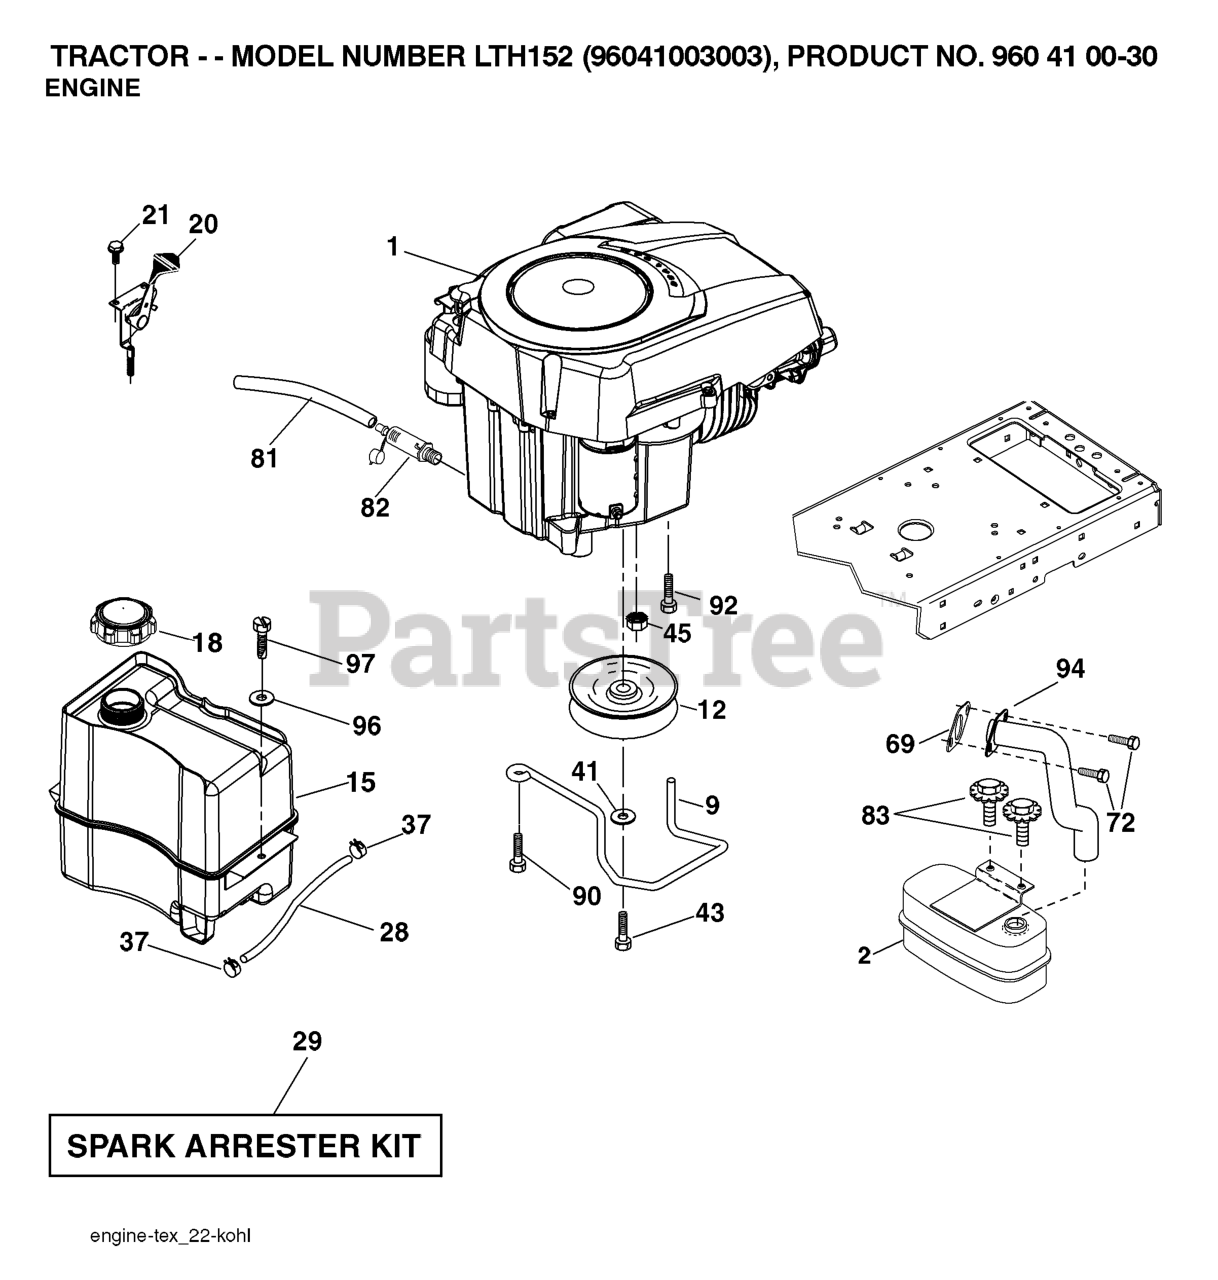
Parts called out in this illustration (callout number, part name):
2	MUFFLER.SINGLE.CYL.KOHL/B&S
9	KEEPER.BELT.ENGINE.3.25 (3 2)
12	PULLEY ENGINE
15	RP TANK FUEL FRT 1.5 GAL
18	FUEL CAP
20	CONTROL.TH/CK.C.
21	SCREW
28	LINE.FUEL.20
29	KIT.SPARK ARRESTOR 794945 B&S
37	HOSE CLAMP
41	LOCKWASHER
43	BOLT HEX 7/16-20X4-1/4"
45	NUT
69	GASKET.EXHAUST.KOHLER
72	SCREW.SOCKET HD.5/16-1
81	TUBE, DRAIN OIL ASM.
82	PLUG DRAIN OIL EASY
83	BOLT.5/16-18UNCX3/4 W/SEMS.BLK
90	SCREW 3/8-16X1
92	SCREW 3/8-16X1
94	RP.TUBE.EXHAUST.KOHL.COURAGE
97	SCREW HEXWSHR 1/4-20X3/4
